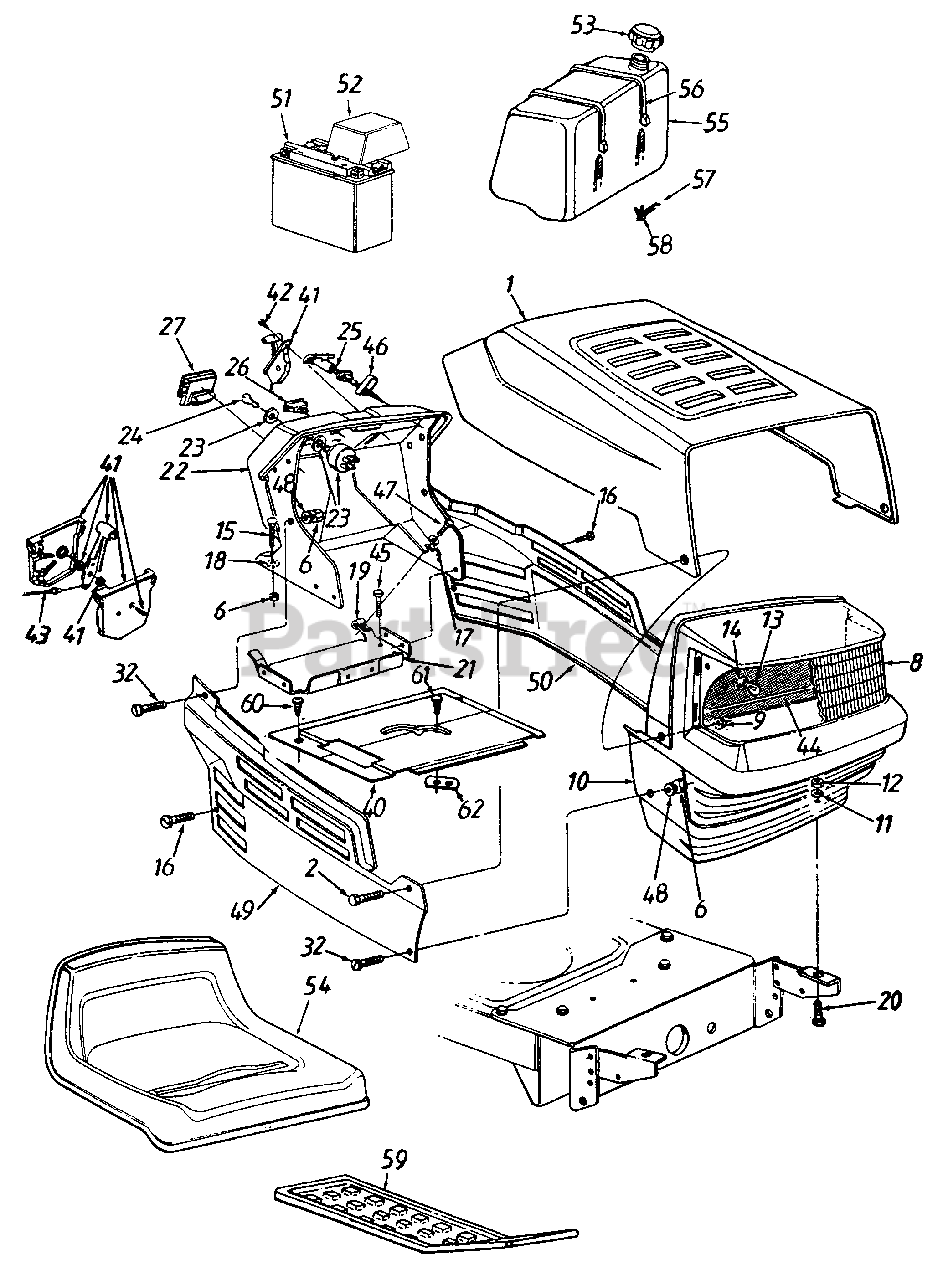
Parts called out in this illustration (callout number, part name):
6	Hex Nut 1/4-20 Thd.
8	Headlight Lens
9	Flange L-Nut 1/4-28 Thd.
10	Grille
11	Fl-Wash. .344" I.D. x 1" O.D.
12	Hex Nut 5/16-18 Thd.
13	Lamp
14	Socket
15	Carriage Bolt 1/4-20 x .75" Lg.
16	Hex Wash. Hd. TT-Tap Scr. 1/4-20 x .5" Lg.
17	Fl-Wash. .281" I.D. x .73" O.D.
18	Bolt Retainer 1/4" I.D.
19	Speed Nut 1/4-20 Thd.
20	Hex Bolt 5/16-18 x .75" Lg.
23	Ignition Switch
24	Ignition Key
25	Choke Control
26	Light Switch
27	Ammeter
42	Truss Mach. AB-Tap Scr. #10 x .5" Lg.
43	Throttle Control Wire
44	Grille Reflector Label
45	Hex Wash. Hd. B-Tap Scr. 5/16-18 x .5" Lg.
46	Choke Retainer
47	Hex TT-Tap Scr. 1/4-20 x .75" Lg.
48	Bell-Wash. 1/4" I.D.
52	Battery Cover
53	Fuel Cap
54	Seat 8-7/8" High
55	Fuel Tank (1-1/4 Gal.)
56	Tie Strap
57	Fuel Line
58	Hose Clamp
59	Rubber Foot Pat - L.H.
60	Truss Mach. B-Tap Scr. #10 x .5" Lg.
61	Hex Wash. Hd. AB-Tap Scr. #8 x .5" Lg.
62	Insulator Nut Plate
